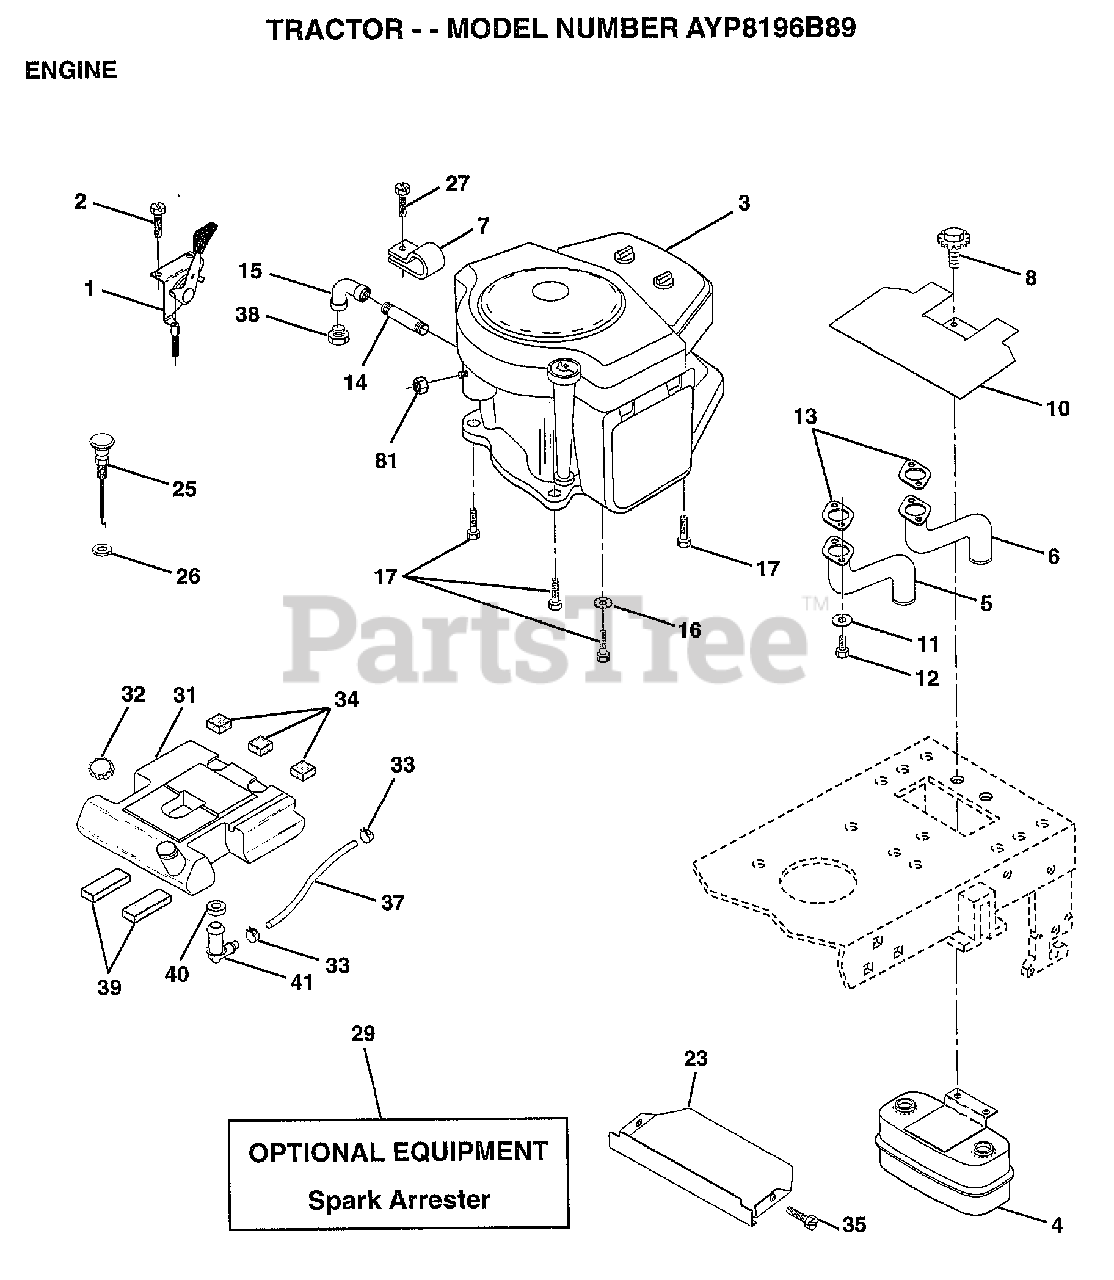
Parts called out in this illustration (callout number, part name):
1	CONTROL THRT 35.5
2	SCREW LT
4	MUFFLER.TW.LOTONE
5	EXHAUST.B&S.18.LH
6	EXHAUST.B&S.18.RH
7	CLAMP.TUBE.DBL.EN
8	BOLT.5/16-18.UNC
10	SHIELD.HEAT.
11	LOCKWASHER
13	GASKET MUFFLER
14	PIPE NIPPLE LT
15	ELBOW
16	LOCKWASHER
17	SCREW LT
23	SHIELD.BRN/DBR.GD
25	CONTROL.CHOKE.37
26	"NUT,KEPS 3/8-24IM"
27	"SCREW-TT,10-32 FL"
31	TANK FUEL REAR
32	CAP ASM FUEL
33	HOSE CLAMP
34	PAD-SPACER LT
35	SCREW
37	FUEL LINE T
39	PAD IDLER TI
40	BUSHING OUTLET T
41	STEM.TANK.FUEL
81	NUT
